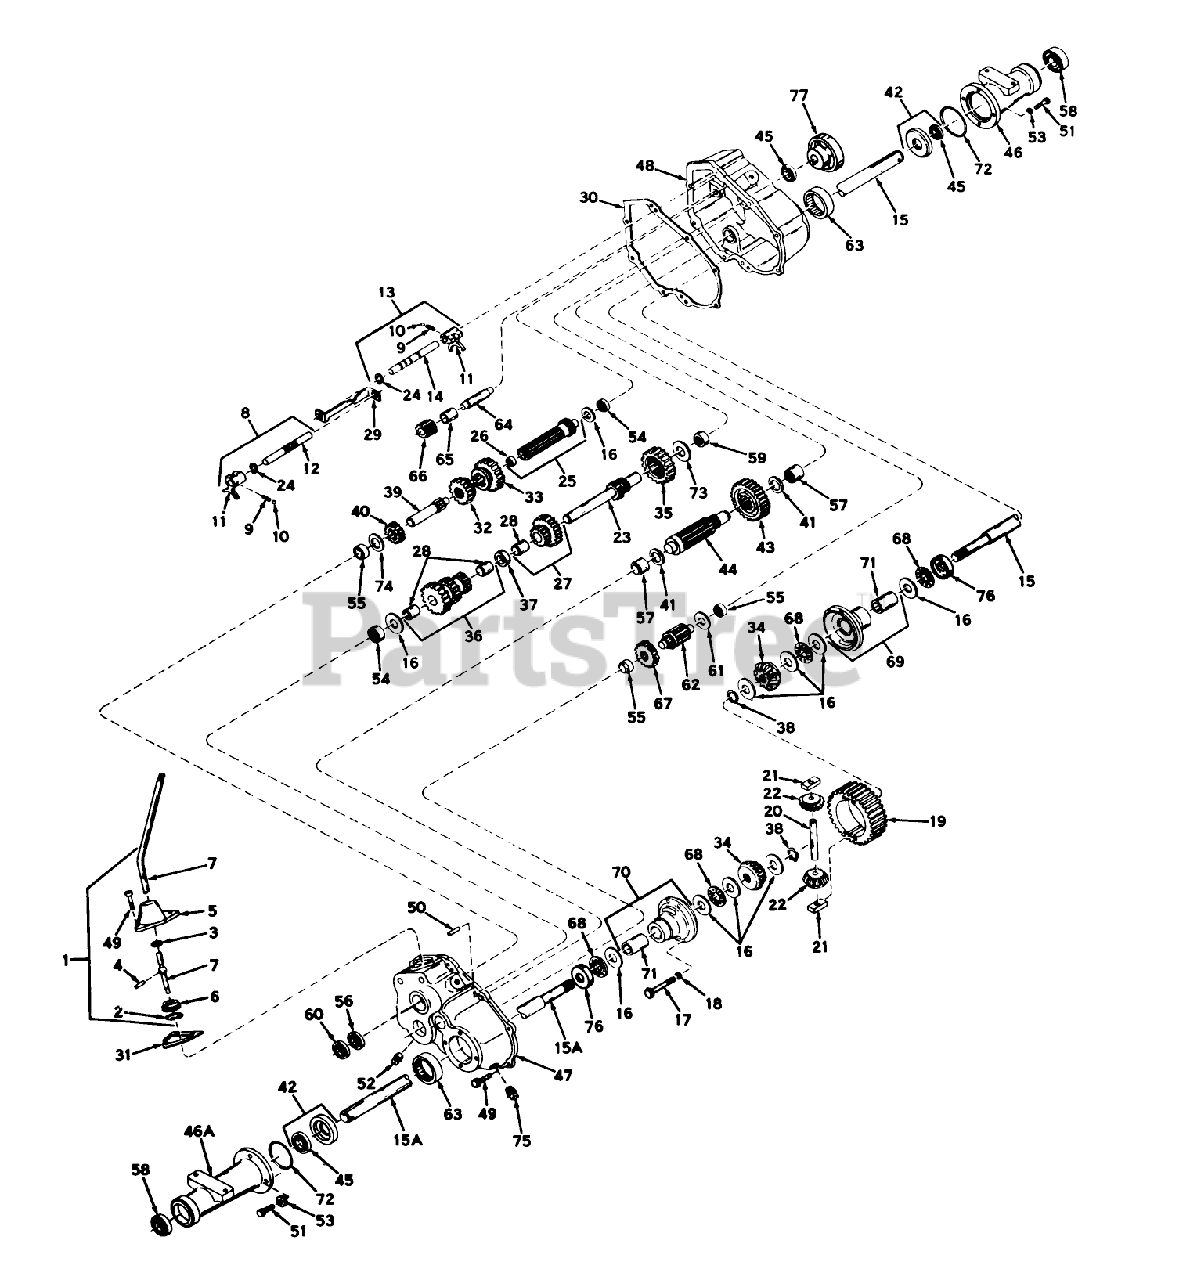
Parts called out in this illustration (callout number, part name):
1	Lever Housing Assy., Shift (Incl. Nos. 2 thru 7)
2	Ring-Snap
3	O Ring
4	Roll Pin
5	Housing-Shift Lever
6	Keeper-Shift Lever
7	Lever, Shift
8	Rod Assy., Shift (Incl. Nos. 9 thru 12 24)
9	Spring
10	Piston ASM
11	Shift Fork
12	Rod, Shifter
13	Rod Assy., Shift (Incl. Nos. 9, 10, 11, 14 24)
14	Rod, Shifter
15	Axle, R.H.
15A	Axle, L.H.
16	Washer
17	Screw (1/4-20 x 2-1/2)
18	Lockwasher
19	Gear, Ring
20	Pin-Drive
21	Biock-Drive
22	Pinion, Bevel
23	Shaft Gear, Brake
24	Ring-Snap
25	Shaft Bearing Assy., Pinion (Incl. No. 26)
26	Bearing
27	Gear Cluster Assy. (Incl. No. 28)
28	Bushing
29	Stop-Shifter
30	Gasket-Case Cover
31	Gasket-Lever Housing
32	Gear, Shifting
33	Gear, Shifting
34	Gear, Bevel
35	Gear-Spur
36	Gear Cluster Assy. (Incl. No. 28)
37	Spacer
38	Ring-Snap
39	Shaft, Input
40	Gear (10 teeth)
41	Washer-Thrust
42	Seal Retainer Assy., Oil(Incl. No. 45)
43	Gear-Output
44	Pinion-Output
45	Seal-Oil
46	Housing, R.H. Axle
46A	Housing, L.H. Axle
47	Case Assy., Transaxle (Incl. Nos. 54, 55, 57 63)
48	Cover Assy., Transaxle (Incl. 54, 55, 57, 59 63)
49	Wire 960
49	Screw
50	Dowel Pin
51	Screw (5/16-18 X 7/8)
52	Plug-Magnetic Drain
53	Lockwasher
54	Bearing-Needle
55	Bearing, Needle
56	Bearing
57	Bearing-Needle
58	Bearing-Ball
59	Bearing-Needle
60	Seal-Oil
61	Washer
62	Shaft Pinion
63	Bearing Needle
64	Shaft-Reverse Idler
65	Spacer-Reverse Idler
66	Idler Reverse
67	Gear-Spur (22 Teeth)
68	Bearing-Thrust
69	Carrier Assy., Differential (Incl. No. 71)
70	Carrier Assy., Differential (Incl. No. 71)
71	Bushing
72	O-Ring
73	Washer-Thrust
74	Washer
76	Race-Thrust
77	Drum, Brake
